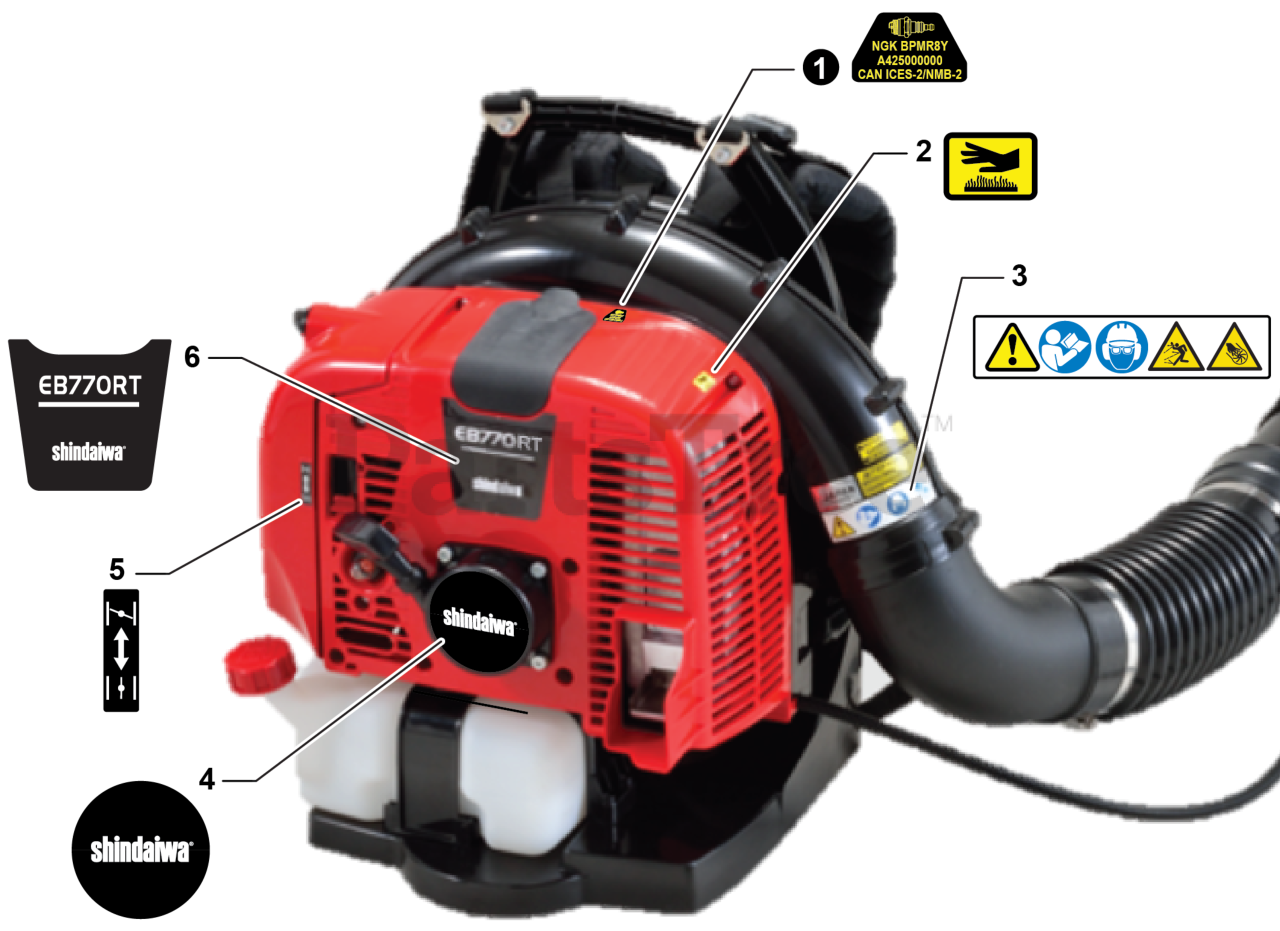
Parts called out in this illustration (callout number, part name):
1	LABEL - SPARK PLUG - BPMR8Y
2	LABEL - CAUTION - HOT
3	LABEL - CAUTION - ISO
4	LABEL - RECOIL STARTER - SHINDAIWA
5	LABEL - CHOKE
6	LABEL - EB770RT
